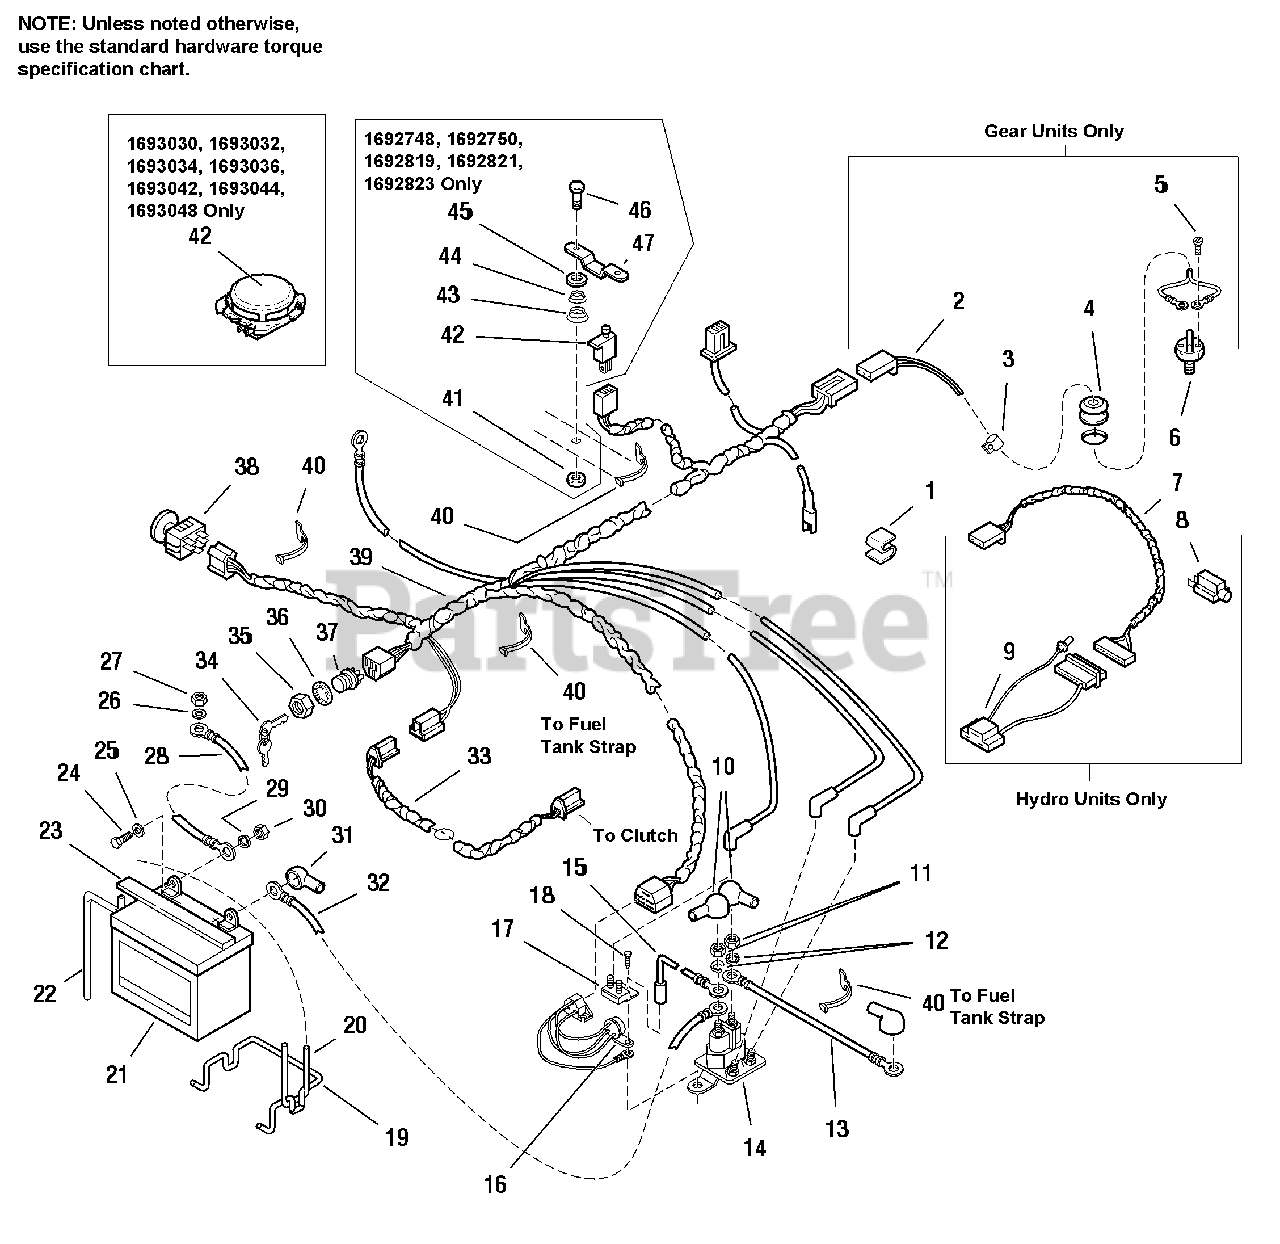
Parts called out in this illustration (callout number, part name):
2	WIRE ASSY., Neutral Switch
3	CLAMP, Wire
5	SCREW, Taptite, #10-20 x 5/8
6	SWITCH, Neutral
7	WIRE ASSY, Neutral Switch
8	SWITCH, Neutral Start
9	ADAPTOR PLUG, Engine
10	COVER, Terminal
11	NUT, Hex, 5/16-24
12	LOCKWASHER, 5/16
13	CABLE, Solenoid to Starter
14	SOLENOID
16	MODULE, Interlock
17	CIRCUIT BREAKER
18	SCREW, Hex, Flange, Taptite, 1/4-20 x 1/2
19	BRACE, Battery
20	STRAP, Battery
23	VENT CAP, Battery
24	CAPSCREW, Hex Hd., 1/4-20 x 3/4
25	WASHER, Plain
26	LOCKWASHER, External Tooth, 3/8
27	NUT, Hex, 3/8-16
28	CABLE, Battery, Ground
29	LOCKWASHER, 1/4
30	NUT, Hex, 1/4-20
31	BOOT, Insulator
32	CABLE, Battery to Solenoid
33	WIRE ASSY., PTO Clutch
34	KEY, Ignition
35	ADAPTER, Nut
36	WASHER, Internal Tooth, 5/8
37	SWITCH, Ignition
38	SWITCH, PTO, Electric Clutch
39	WIRING HARNESS
40	TIE, Self-Locking
41	NUT, Hex, Nylon Lock, 5/16-18
42	SWITCH, Seat
45	WASHER, Flat, 13/32 x 7/8 x 5/64
46	CAPSCREW, Hex Hd., 5/16-18 x 1-3/4
47	PLATE, Seat Actuator
